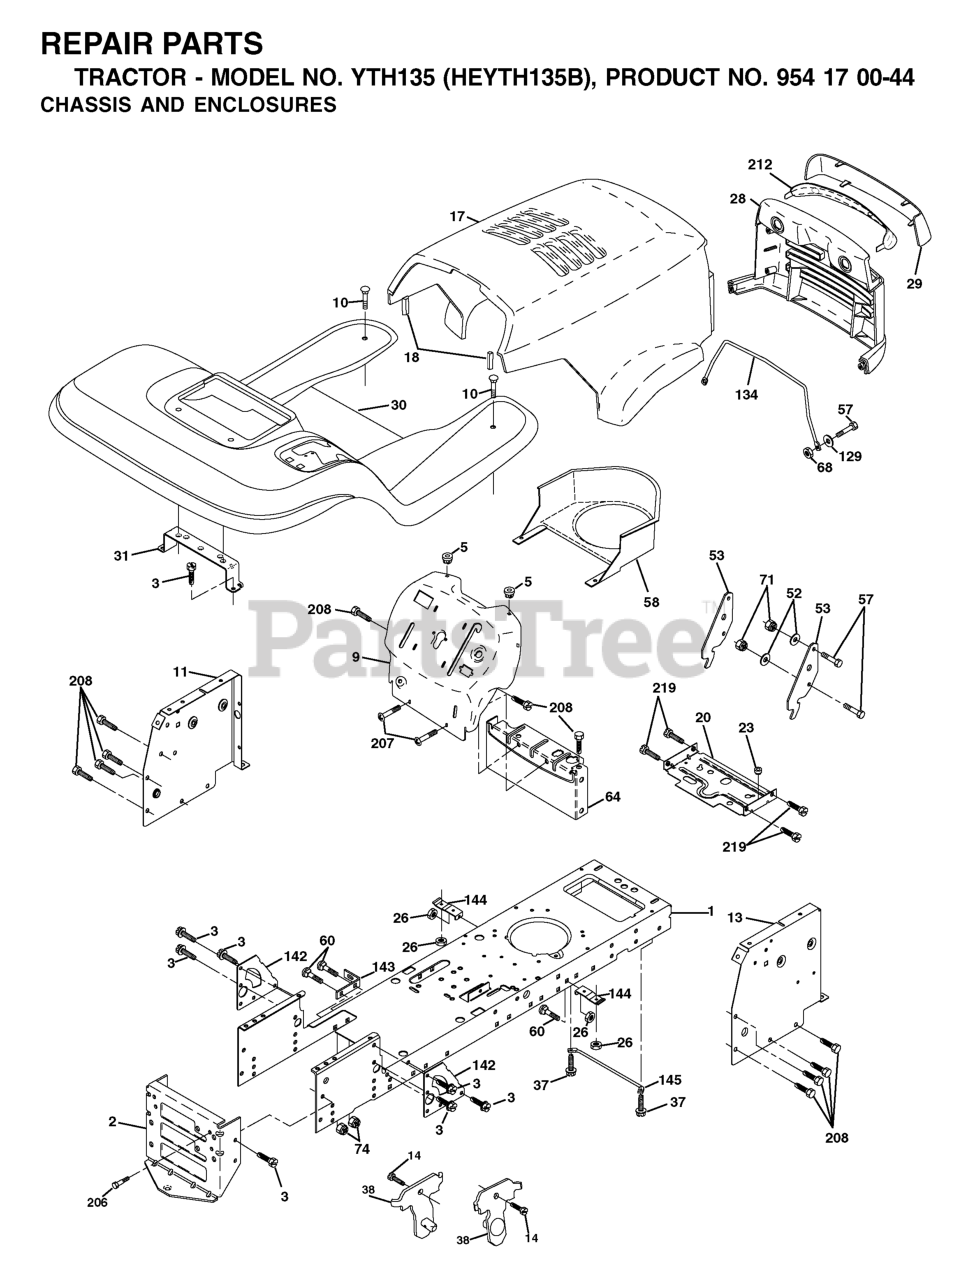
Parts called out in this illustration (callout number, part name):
1	CHASSIS STAMPING
2	DRAWBAR, 12GA
3	SCREW 3/8-16X3/4
5	BUMPER.RUBBER.HOOD
9	DASH
10	BOLT D
11	PANEL DASH LH
13	DASH PANEL ASM.
17	HOOD
18	BUMPER HOOD T
20	PLATE MTG.BATTERY/FUEL TANK
23	BUSHING.SNAP.NYL.BLK.
25	WASHER
26	NUT
28	GRILL
29	LENS
30	FENDER FOOTREST
31	BRACKET.SUPPORT.FENDER
37	Screw 5/16-18 x 1/2 Hex, Self Tapping 5/16-18 x 1/2
38	BRACKET.ASM.PIVOT.MOWER.REAR
53	BRACKET PNT PICK OFF LT/PL
57	BOLT
58	AIR DUCT P/L/LT
60	Bolt - Rd. Hd. Sq. Neckiage 3/8 16 x 3/4
64	DASH LOWER
68	NUT
71	NUT.CROWNLOCK.1/4
134	ROD SUPPORT HOOD LT/PL HUS.
142	PLATE REINFORCEMENT
143	BRACKET, SWAY BAR
144	BRKT, FOOT REST
145	ROD PIVOT CHASSIS/HOOD
206	SHOULDER BOLT 5/16-18TT
207	SCREW, 5/16-18 X 1/2
208	SCREW 3/8-16X1/2
212	INSERT LENS REFLECTOR
